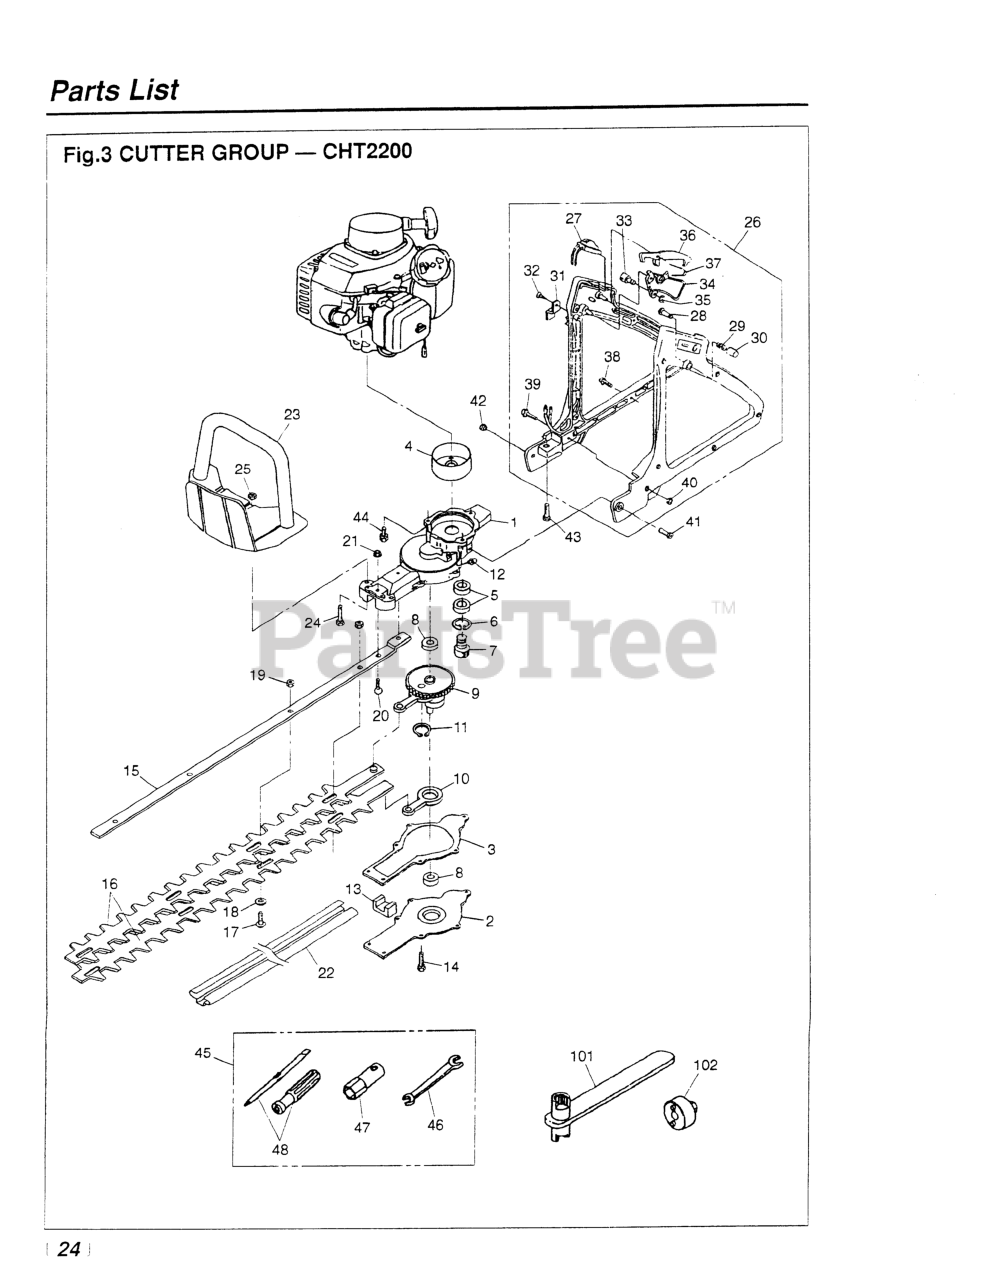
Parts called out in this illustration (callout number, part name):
1	GEARCASE
2	COVER
3	GASKET
4	DRUM, CLUTCH
5	BEARING
6	RING, SNAP
7	PINION
9	GEAR COMPL
10	ROD
11	RING, SNAP, M25 X 1.2
12	FITTING, GREASE
13	FELT
14	BOLT
15	PLATE, GUIDE
16	BLADE
18	WASHER (RPLS 3873-11760)
19	NUT, M6
20	SCREW
21	NUT
22	COVER, BLADE
23	HANDLE, FRONT
24	BOLT, M6x35 (RPLS -50635)
25	NUT, M6 X 5
26	HANDLE, REAR ASSY (RPL 3873-)
27	SWITCH
29	SPRING
30	CAP, PIN
31	PLATE
32	SCREW, M4 x 10
33	END, CABLE
34	LEVER, THROTTLE (RPLS -13220)
35	RING, SNAP
37	SPRING (REPLACES -13321)
38	SCREW, M4 X 16
39	SCREW, M4 x 30
40	NUT, M6 X 4
41	BOLT, M6 X 50
42	NUT, M6 X 5
43	BOLT, M6 X 40
44	BOLT, M6 X 14
45	TOOL SET
46	SPANNER, 8 X 10 (RPLS 2540- )
47	SOCKET, HEX, 3/4
48	SCREWDRIVER
102	WRENCH (TOOL)
